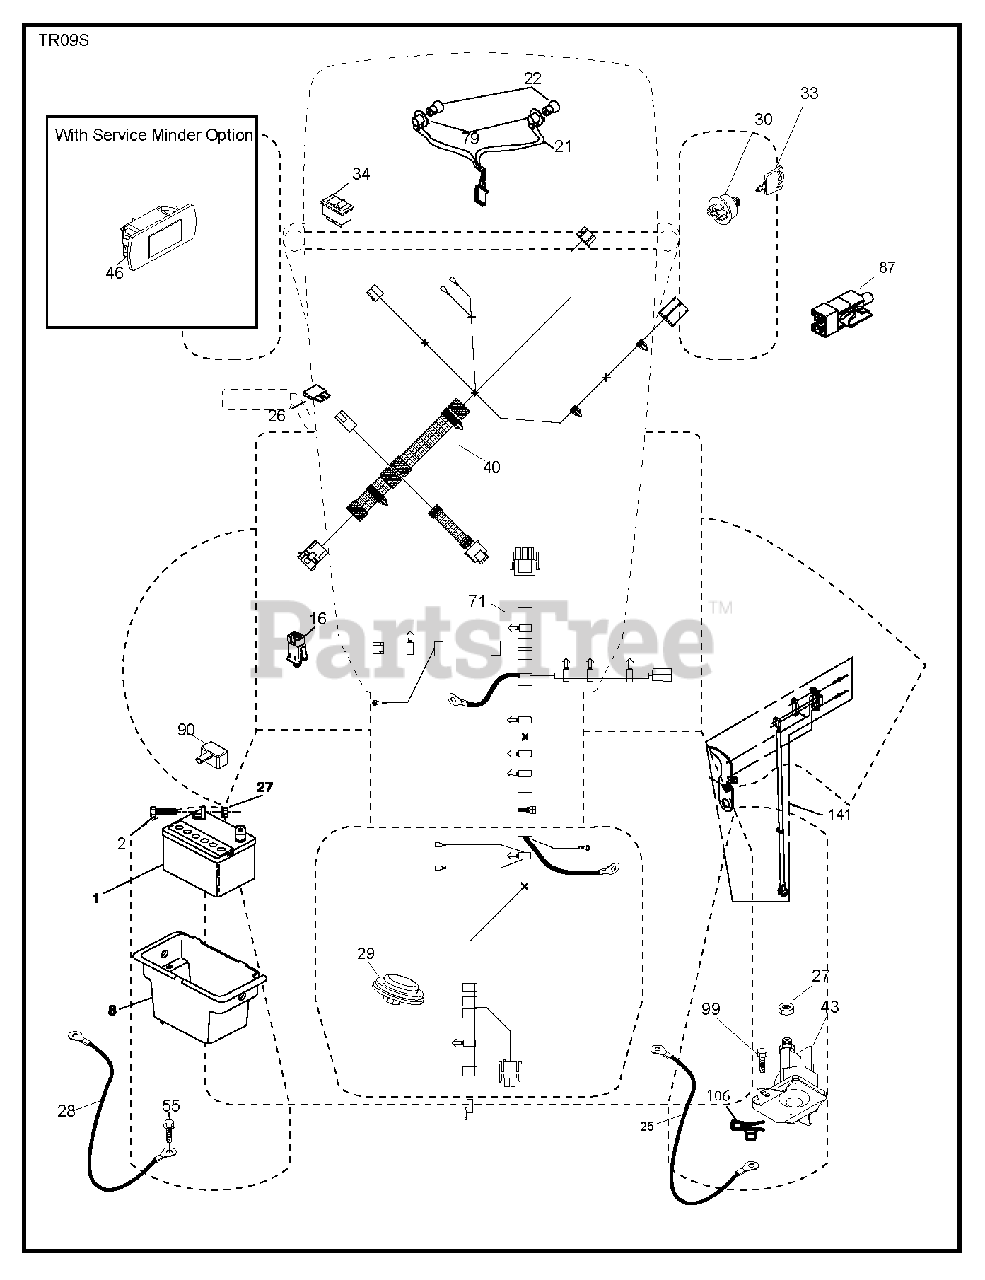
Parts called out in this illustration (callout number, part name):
2	BOLT.HEX.1/4.X.3/4.DICHROMATE
8	BOX.BATTERY.MNT.REAR.L
16	SWITCH INTERLOOK PUSH-IN
21	HARNESS.LIGHT W/4152J BULBS
22	LIGHTBULB
25	CABLE.BATT.RED.8GA.17
26	FUSE 20AMP
27	NUT
28	CABLE.GROUND.REAR.BATTERY.8G
29	SWITCH.SEAT.DELTA.OPC.
30	SWITCH.IGN.DELTA.W.LGH.ROS
33	KEY.CHAIN.BLISTER.PACK.GEN.USA
34	SWITCH LT
40	HARNESS.TEX.DASH.MAN.REAR BATT
43	SOLENOID.W/BRASS.PLUNGER
55	SCREW 5/16"
71	HARNESS.TEX.CHSSIS.REAR.BATT
79	BULB HOLDER ASM.
87	SWITCH.INTRLCK.CLUTCH.
90	COVER.TERMINAL.BATTERY
99	SCREW HEXWSHR 1/4-20X3/4
106	1/4-20 U NUT
141	KIT T2.ROS 71677
